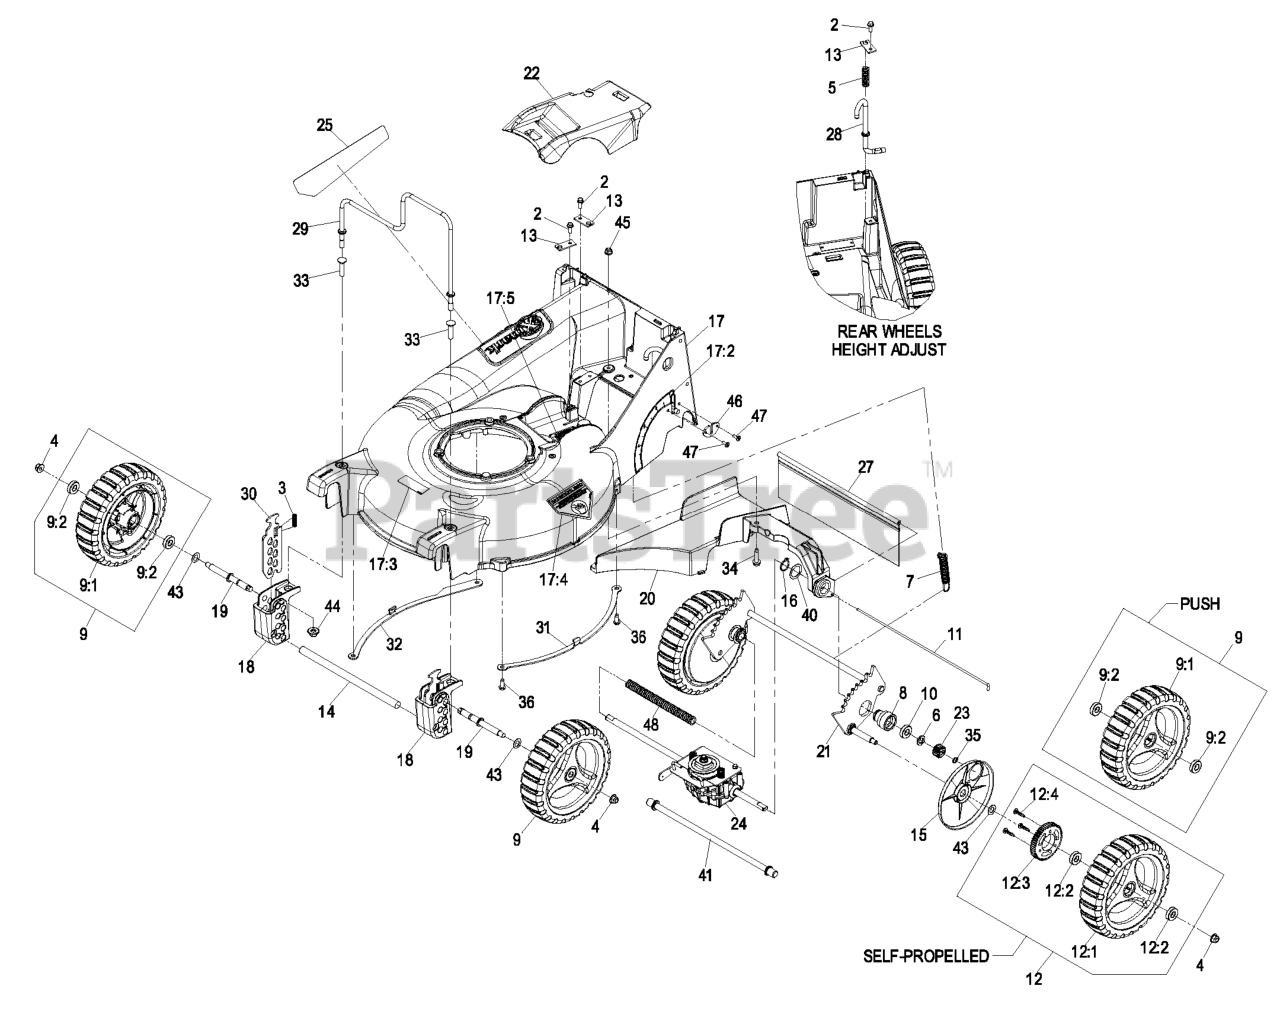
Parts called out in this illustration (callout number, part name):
2	SCREW-HWH
3	SPRING-COMPRESSION
4	NUT-HF, NI
5	SPRING-COMPRESSION
6	SPACER-BUSHING
7	SPRING-EXTENSION
9:2	BEARING-BALL
10	BEARING-BALL
11	ROD,SHIELD
12:2	BEARING-BALL
12:4	SCREW-DRIVE
13	BRACKET,MOUNT
14	ROD,BUMPER
15	COVER,GEAR
16	RING-RETAINING
17	DECK W/DECALS
17:2	DECAL-HEIGHT OF CUT
17:3	DECAL-BLADE
17:4	DECAL-DANGER
17:5	DECAL-COVER MISSING
18	BLOCK,FRONT QUADRANT
19	AXLE-WHEEL
21	WLD,REAR AXLE P21
22	COVER,BELT
24	ASM,TRANSMISSION W/BRACKE
25	DECAL,COMMERCIAL 21 AS
27	SHIELD-TRAILING P21
28	ROD-HEIGHT ADJ P21
29	GUARD,ENGINE
30	PLATE, FRONT HEIGHT
31	SKID,LH
32	SKID,RH
33	SCREW-CARR
34	SCREW-HWHTF
35	RING-RETAINING
36	SCREW-BHTF
41	SPACER-HOUSING
43	WASHER-PLAIN
44	Nut-Nyloc 3/8-16 Flg
45	NUT-HF, NI
46	PLATE,WEAR
47	RIVET-BLIND
48	COVER-SHAFT, DRIVE
